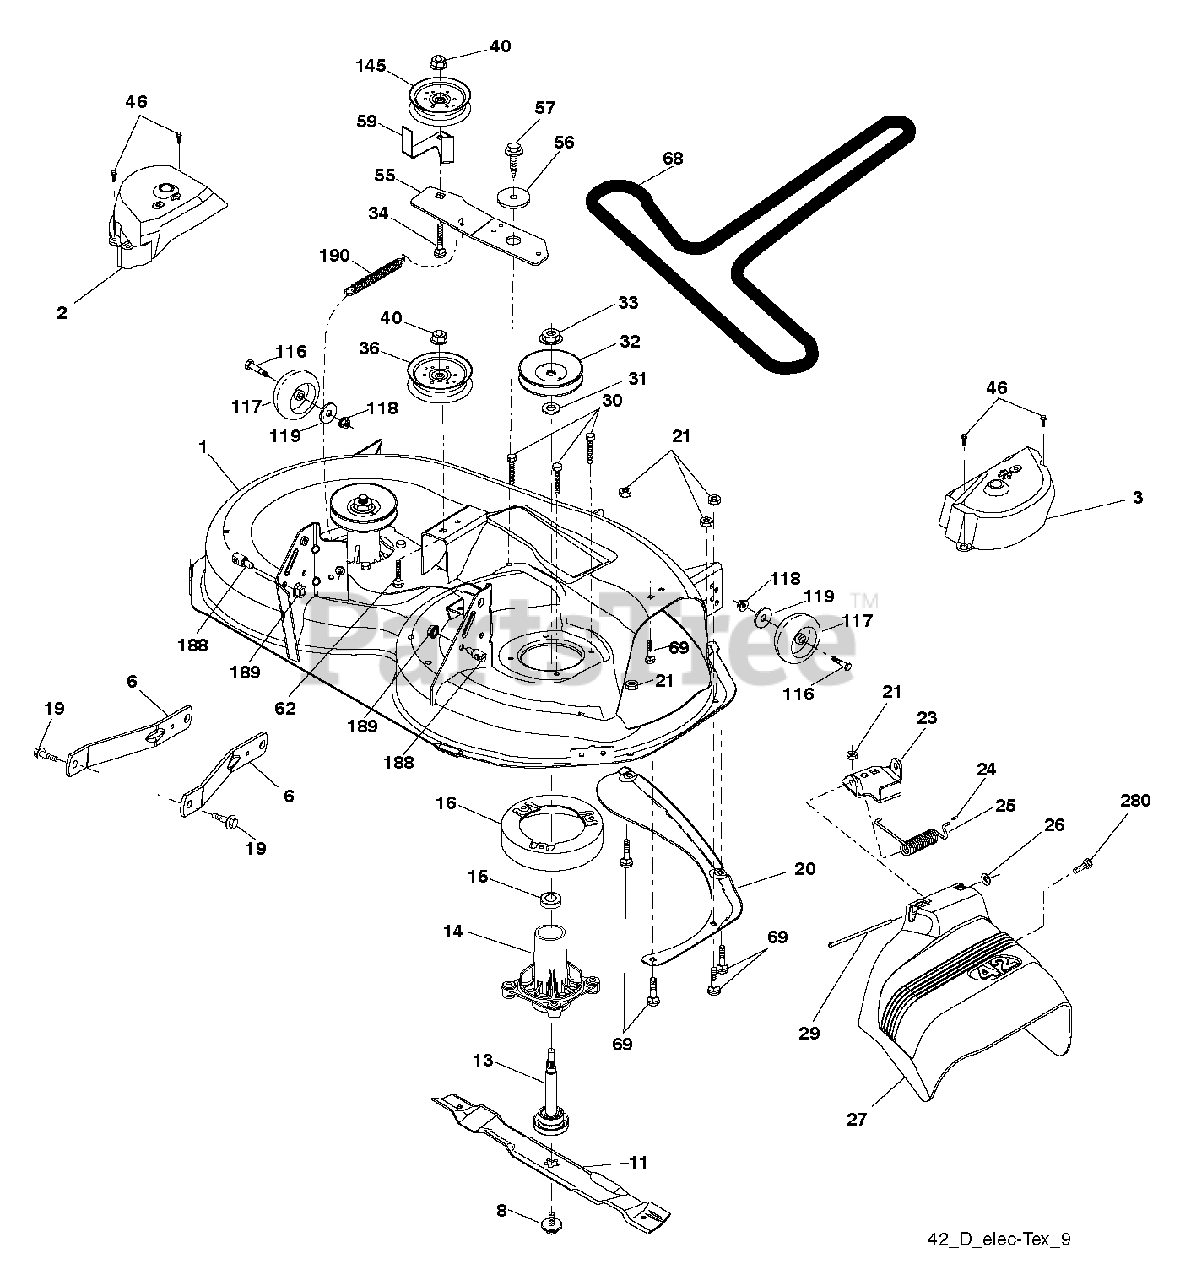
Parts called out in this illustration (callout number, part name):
1	DECK.WELDMENT.42"
6	ARM.SUSPENSION.MOWER.R
8	BOLT.WASHER.ASM.7/16-2
11	42" HI-LIFT BLADE
13	SHAFT.ASM.MDRL.N/GREASE.38
14	HOUSING MANDREL
16	STRIPPER, MWR ROUND
19	BOLT.SHOULDER
20	BAFFLE.VORTEX
21	LOCKNUT
23	BRKT.DEFLECTOR.38"2005+
24	CAP-SLEEVE LT
25	SPRING.TORSION.DEFLECT
26	NUT PUSH M
29	ROD.HINGE
30	SCREW, WASHER HEAD
31	WASHER.SPACER.MANDREL
32	PULLEY/MANDREL
33	NUT.FLANGE.LOCK.TOP
34	BOLT.3/8-16X1.50
36	PULLEY.IDLER.2006
40	NUT LOCK FLG 3/8-16 UNC
46	SCREW.1/4-20X5/8
55	IDLER.ARM
56	SPACER.RETAINER
57	SCREW 3/8-16X1
59	GUARD, BELT
62	BOLT
68	BELT V SECONDARY
69	BOLT
117	WHEEL.GAGE.HALF.SPOKED
118	LOCKNUT
119	WASHER
145	PULLEY.IDLER.48"PRIMARY
188	STUD.FASTNER.W/ANTI-ROTATE
189	NUT LOCK HEX FLANGE 5/16-18
190	SPRING.MOWER.DRIVE.ELECTRIC
280	SCREW 3/8-16X1/2
